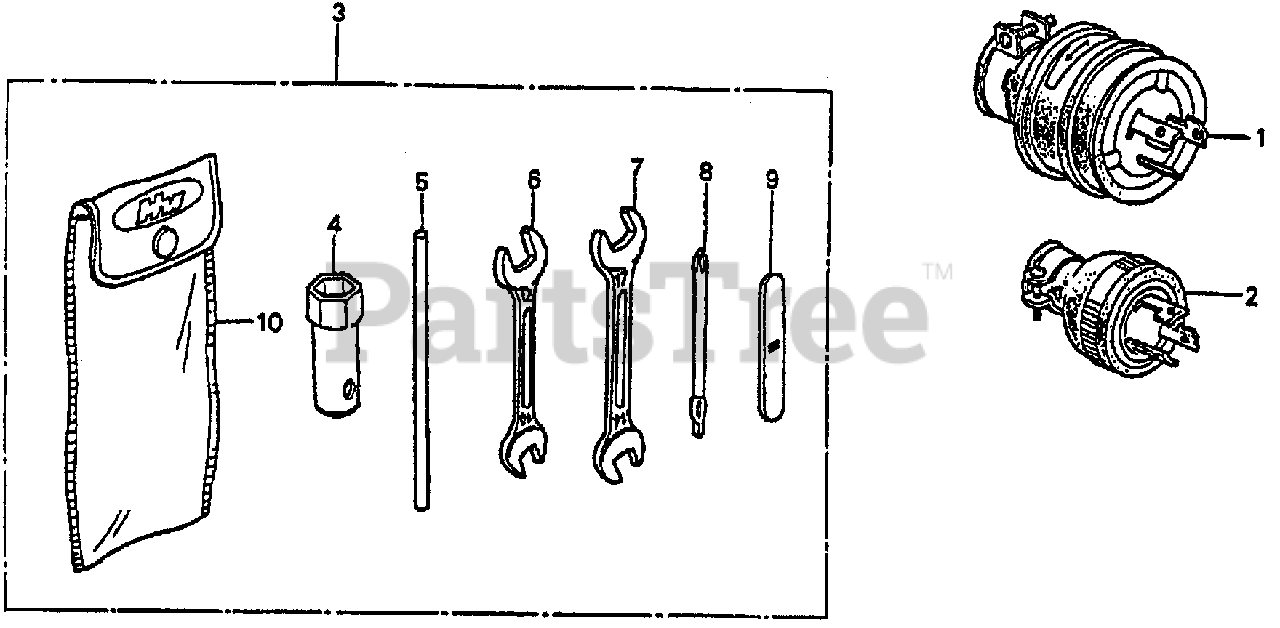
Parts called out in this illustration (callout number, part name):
1	PLUG ASSY., RECEPTACLE (30A-250V)
2	PLUG ASSY., RECEPTACLE (20A-250V)
4	WRENCH, BOX (P21) (NOT AVAILABLE)
5	HANDLE, BOX WRENCH
6	SPANNER (10X12)
7	SPANNER (14X17)
8	DRIVER 1, PLUS SCREW (NO.2)
9	LEVER, TIRE
